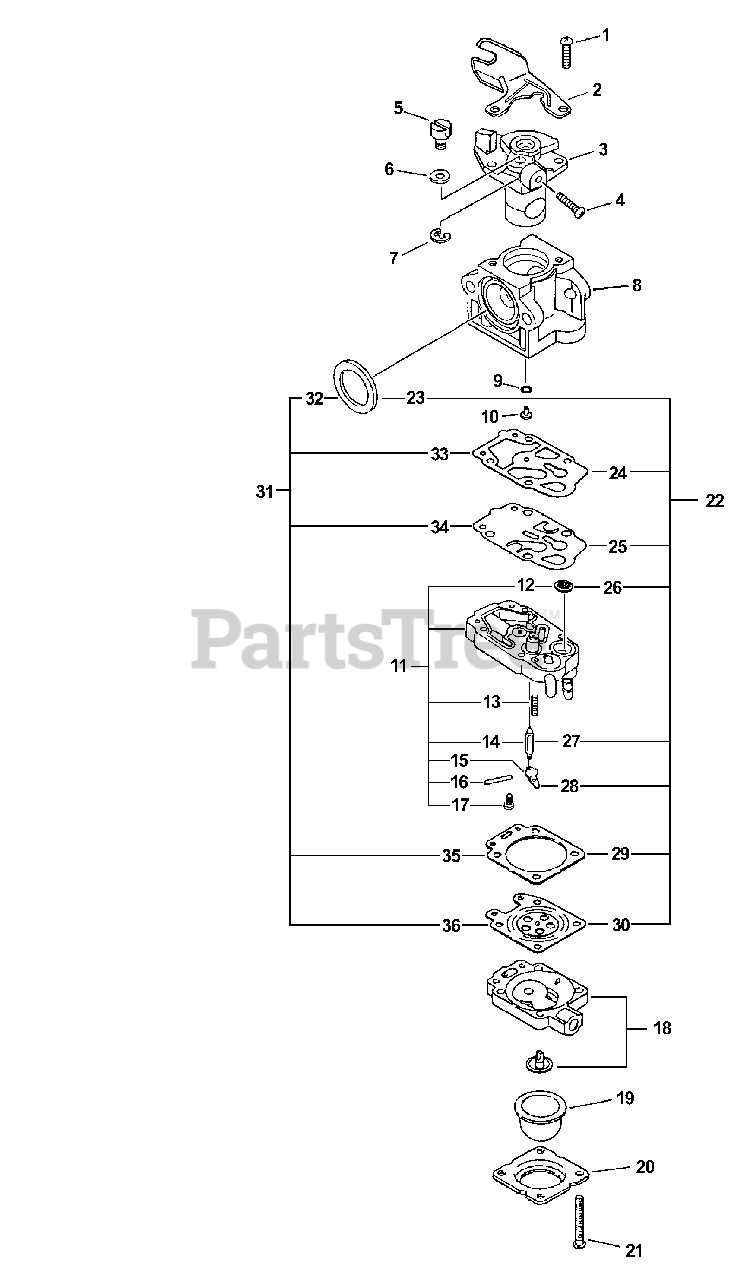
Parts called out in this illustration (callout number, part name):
2	BRACKET, CABLE
3	THROTTLE VALVE ASSY
4	SCREW, IDLE ADJUST
7	RING, RETAINING
8	BODY, CARBURETOR
11	BASE, PURGE
12	STRAINER
13	SPRING, METERING LEVER
14	VALVE, INLET NEEDLE
15	LEVER, METERING
16	PIN, METERING LEVER
17	SCREW, METERING LEVER PIN
18	PURGE BASE ASSY
19	BULB, PURGE
20	RETAINER, PURGE BULB
21	SCREW, PUMP COVER
22	REPAIR KIT
23	SEAL
24	GASKET, PUMP
25	DIAPHRAGM, PUMP
26	STRAINER
27	VALVE, INLET NEEDLE
28	LEVER, METERING
29	GASKET, METERING
30	DIAPHRAGM, METERING
31	DIAPHRAGM/GASKET KIT
32	SEAL
33	GASKET, PUMP
34	DIAPHRAGM, PUMP
35	GASKET, METERING
36	DIAPHRAGM, METERING
